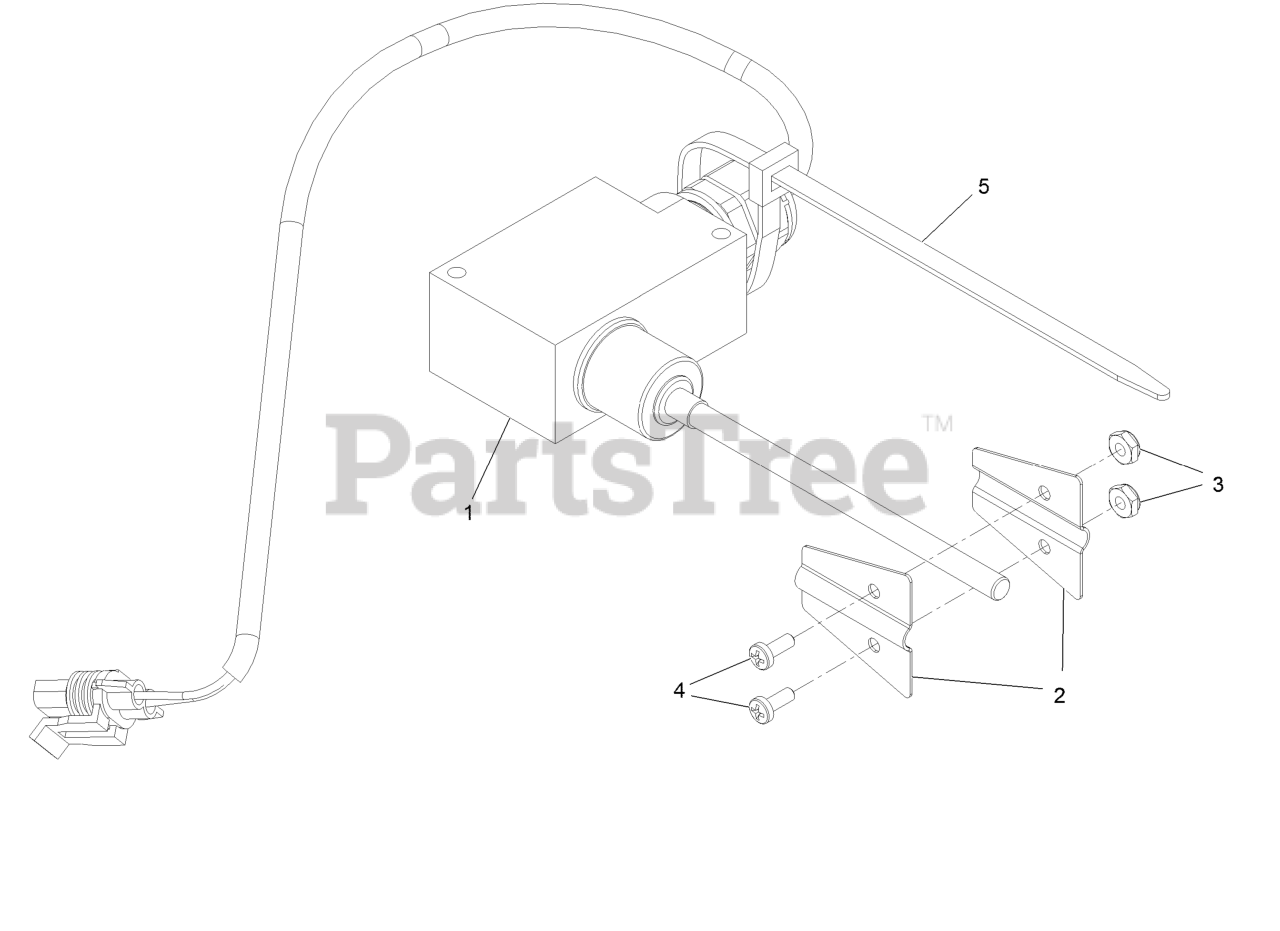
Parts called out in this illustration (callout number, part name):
1	Fill Sensor Wire Kit
2	Flag-Sensor, Fill
3	Nut-Nyloc #6-32 Thin
4	Screw-PPH #6-32 X 5/8
5	Tie-Cable 7 15/16 (Large)
